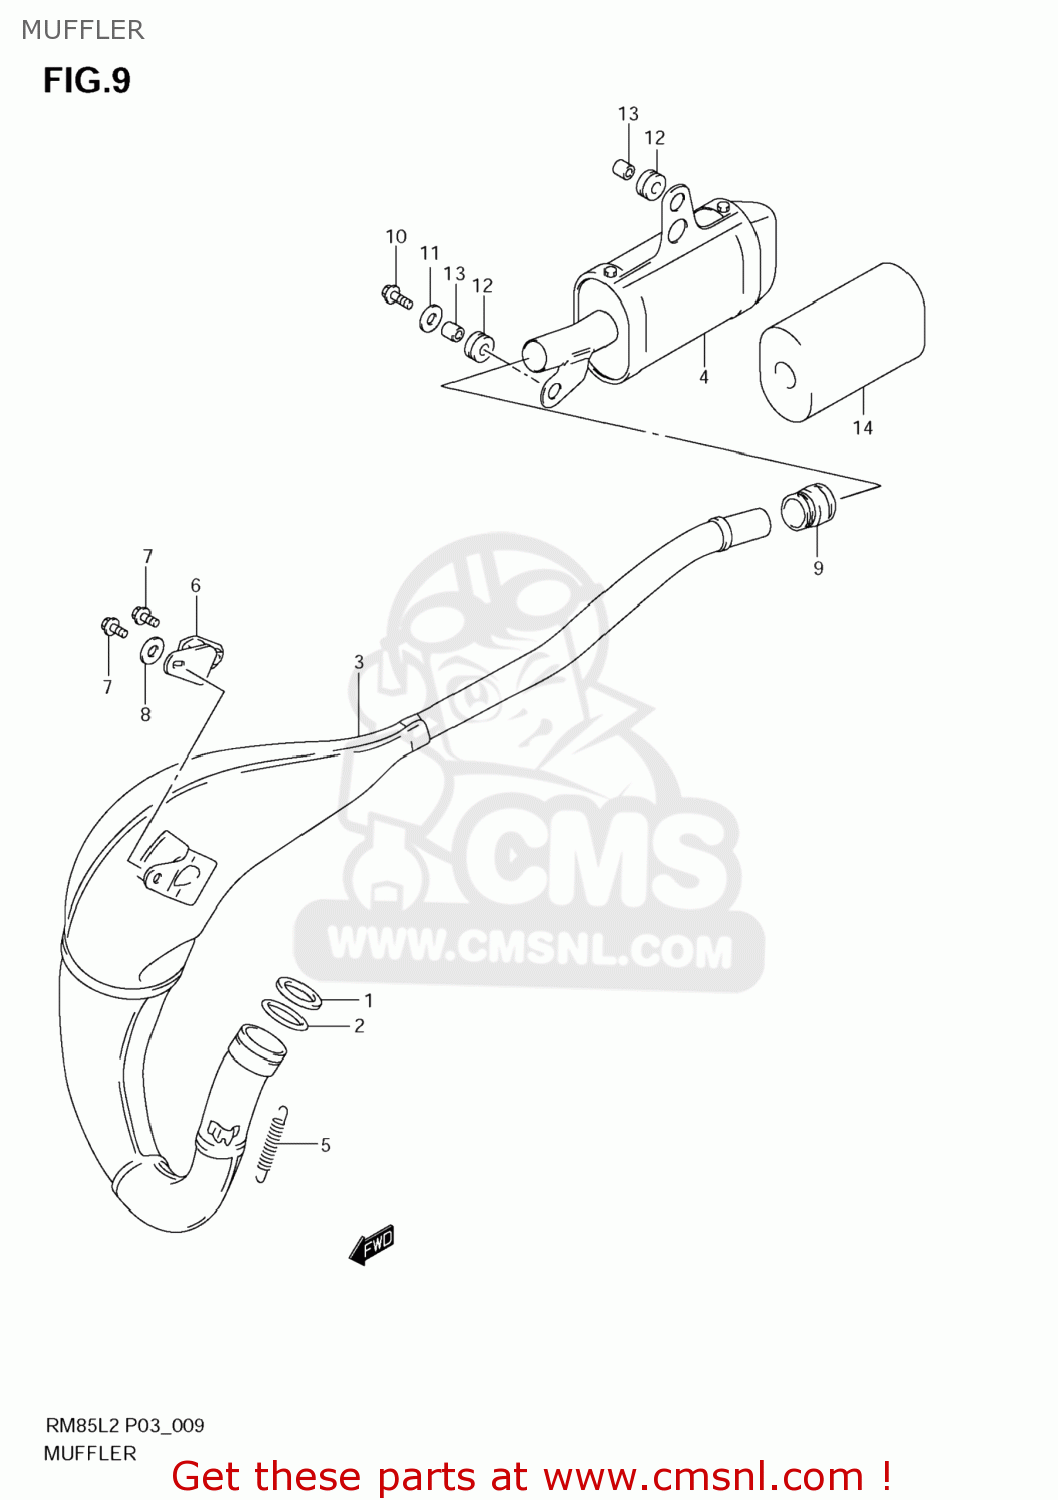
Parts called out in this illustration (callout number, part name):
1	GASKET,EXHAUST PIPE (NAS)
2	O RING,EXHAUST FLANGE
3	BODY,MUFFLER 1ST
4	BODY,MUFFLER 2ND
5	SPRING
6	DAMPER,MUFFLER
7	BOLT(6X12)
8	WASHER(6.5X16X1.2)
9	CONNECTOR,MUFFLER
10	BOLT
11	WASHER(6.5X20X1.2)
12	CUSHION
13	SPACER(6.5X9X8)
14	SILENCER,MUFFLER
